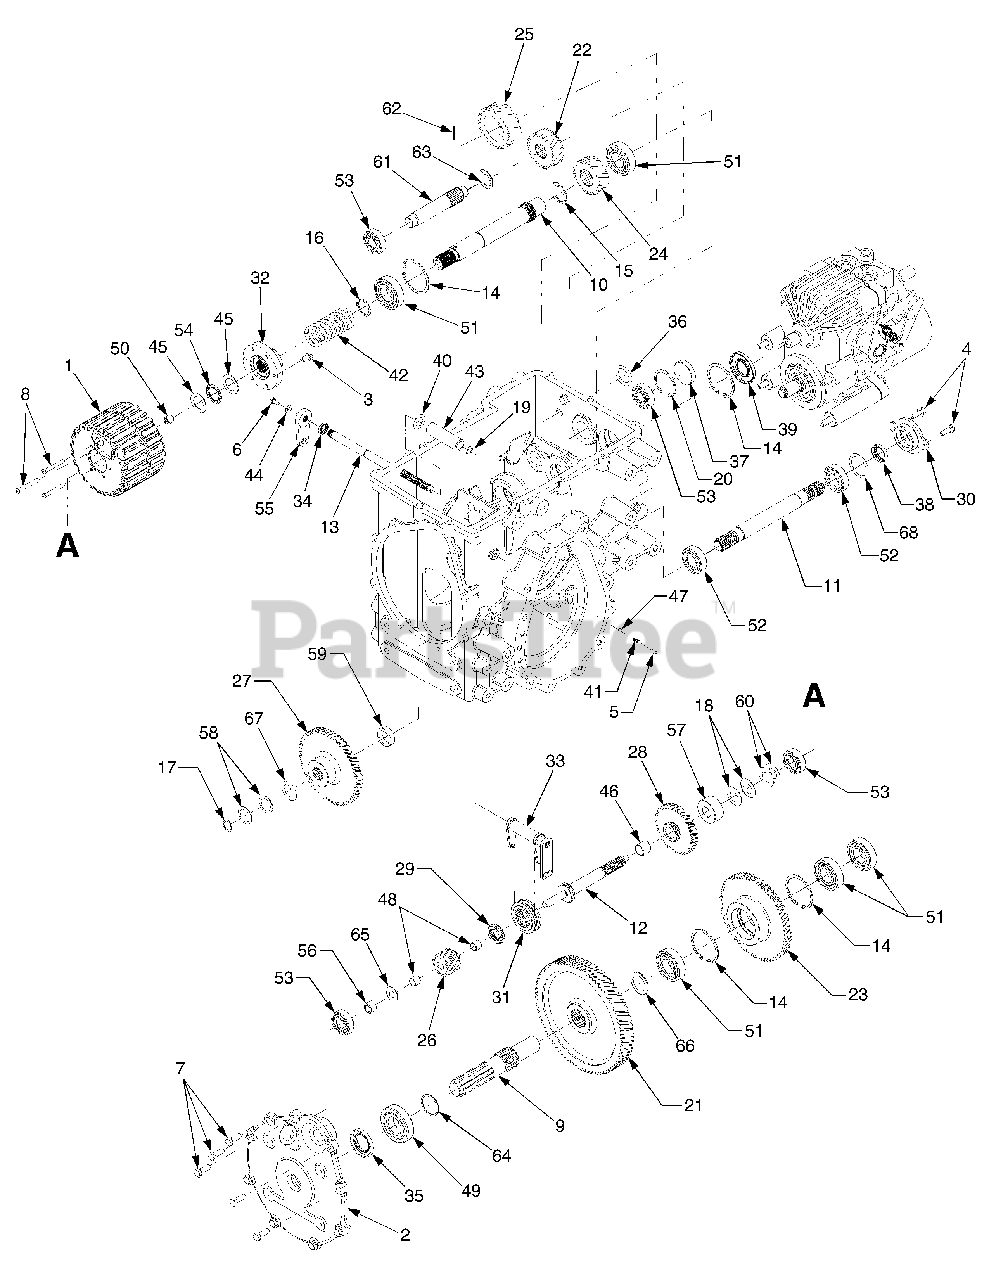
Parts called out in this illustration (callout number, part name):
1	Clutch Assembly, PTO
2	Housing, Rear
3	Screw, Hex Cap Lock, 1/4-20 x .62
4	Screw, Hex Wash Hd, 5/16-18 x .875 GR5
5	Screw, Cup Set, 5/16-18 x 3/8
6	Screw, Hex Cap, 1/4-20 x .5 GR5
7	Screw, Hex Cap Lock, 3/8-16 x 1.0 GR5
8	Screw, Round Hd, 6mm x 40mm
9	Shaft, 540 PTO
10	Shaft, PTO Input
11	Shaft, 2000 PTO
12	Shaft, PTO Back
13	Shaft, PTO Actuator
14	Ring, Retaining
15	Ring, Retaining
16	Ring, Retaining
17	Ring, Retaining
18	Washer, Flat, .793 x 1.368 x .01
19	Ring, Retaining
20	Ring, Retaining
21	Gear, 540 PTO: 81T
22	Gear, Auxiliary Drive Idler: 28T
23	Gear, 2000 PTO: 61T
24	Gear, Auxiliary Drive Pinion: 28T
25	Gear, Auxiliary Drive: 32T
26	Gear, 540 PTO Pinion: 14T
27	Gear, 2000 PTO Pinion: 54T
28	Gear, 2000 PTO Pinion: 34T
29	Gear, Spline Coupling
30	Cover, 2000 PTO
31	Collar, 2 Speed
32	Coupling, PTO
33	Actuator, PTO
34	Seal, Oil
35	Seal, Oil
37	Plug, Oil
38	Seal, Oil
39	Seal, Oil
40	Washer, Hrdn, .58 x 1.06 x .02
40	Washer, Hrdn, .58 x .875 x .01
41	Spring, Detent
42	Spring, Compression
43	Spacer, .568 x .75 x 2.68
44	Washer, Flat, .25 x .630 x .0515
45	Washer, Thrust, 1.007 x 1.542 x .03
46	Bearing, Sleeve, 20mm x 23mm x 20mm
47	Ball, Detent
48	Bearing, Sleeve, 13mm x 15mm x 10mm
49	Bearing, Ball
50	Bearing, Needle
51	Bearing, Ball
52	Bearing, Ball
53	Bearing, Ball
54	Bearing, Needle Thrust
55	Arm, PTO Select
56	Spacer, 13mm x 20mm x 14mm
57	Spacer, .80 x 1.85 x .855
58	Washer, Flat, .865 x 1.145 x .03
59	Spacer, 1.0 x 1.25 x .39
60	Washer, Flat, .793 x 1.368 x .025
61	Shaft, Aux. Idler
62	Pin, Cotter, 1/16 x .5
63	Ring, Retaining ‘E’
64	Ring, Retaining
65	Washer, Shim, .508 x 1.0 x .020
66	Washer, Shim, 1.25 x 1.8 x .020
66	Washer, Shim, 1.25 x 1.8 x .005
66	Washer, Shim, 1.25 x 1.8 x .010
67	Washer, Shim, .915 x 1.37 x .01
68	Washer, Shim, 1.515 x 2.0 x .005
68	Washer, Shim, 1.515 x 2.0 x .015
